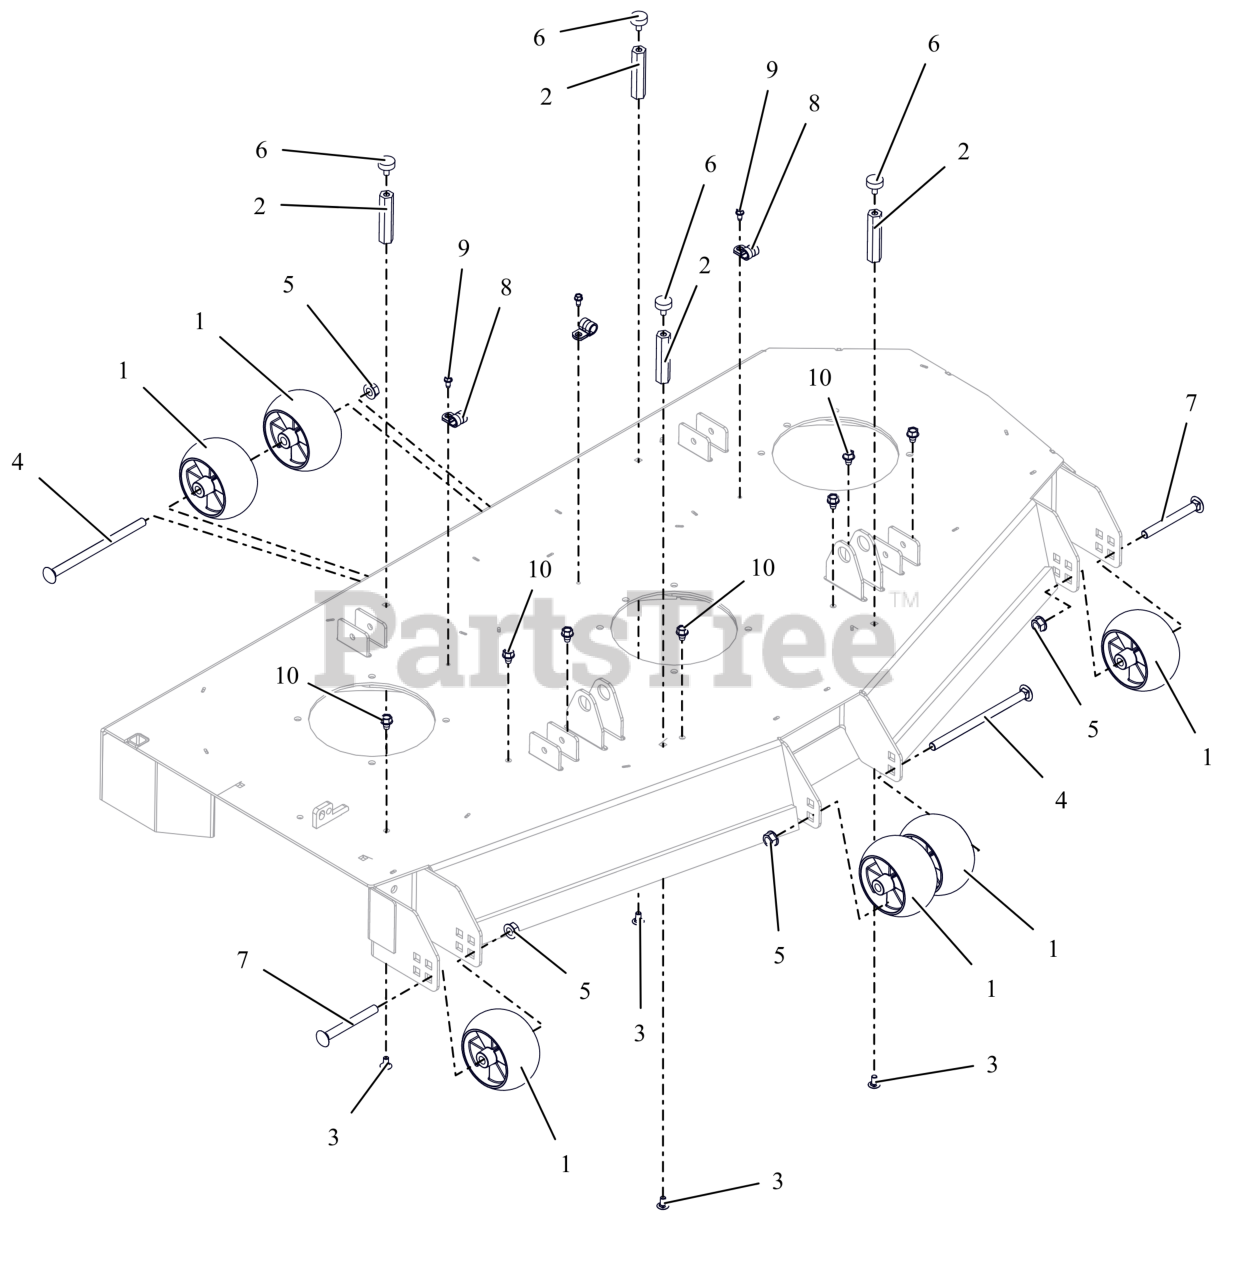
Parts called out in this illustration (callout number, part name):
1	WHEEL, ANTI SCALP - 5X3 CTR W/RIBS
2	NUT, COUPLING .312-18 X 3.375
3	BTL,RHSSN .313-18 X 0.625 G5 ZCC
4	BLT,RHSN .50-13X8.00 G5 ZCC NS
5	NUT-LK-CTR-FLG .500-13 GG ZCC
6	BUMPER, RUBBER
7	BLT,RHNS .50-13X4.50 G5 ZCC NS
8	CLAMP, CUSHIONED STEEL
9	SCR-TAP .25-20X.50 HWH ZCC
10	SCR,TAP .375-16X.50 HWH TR ZCC
